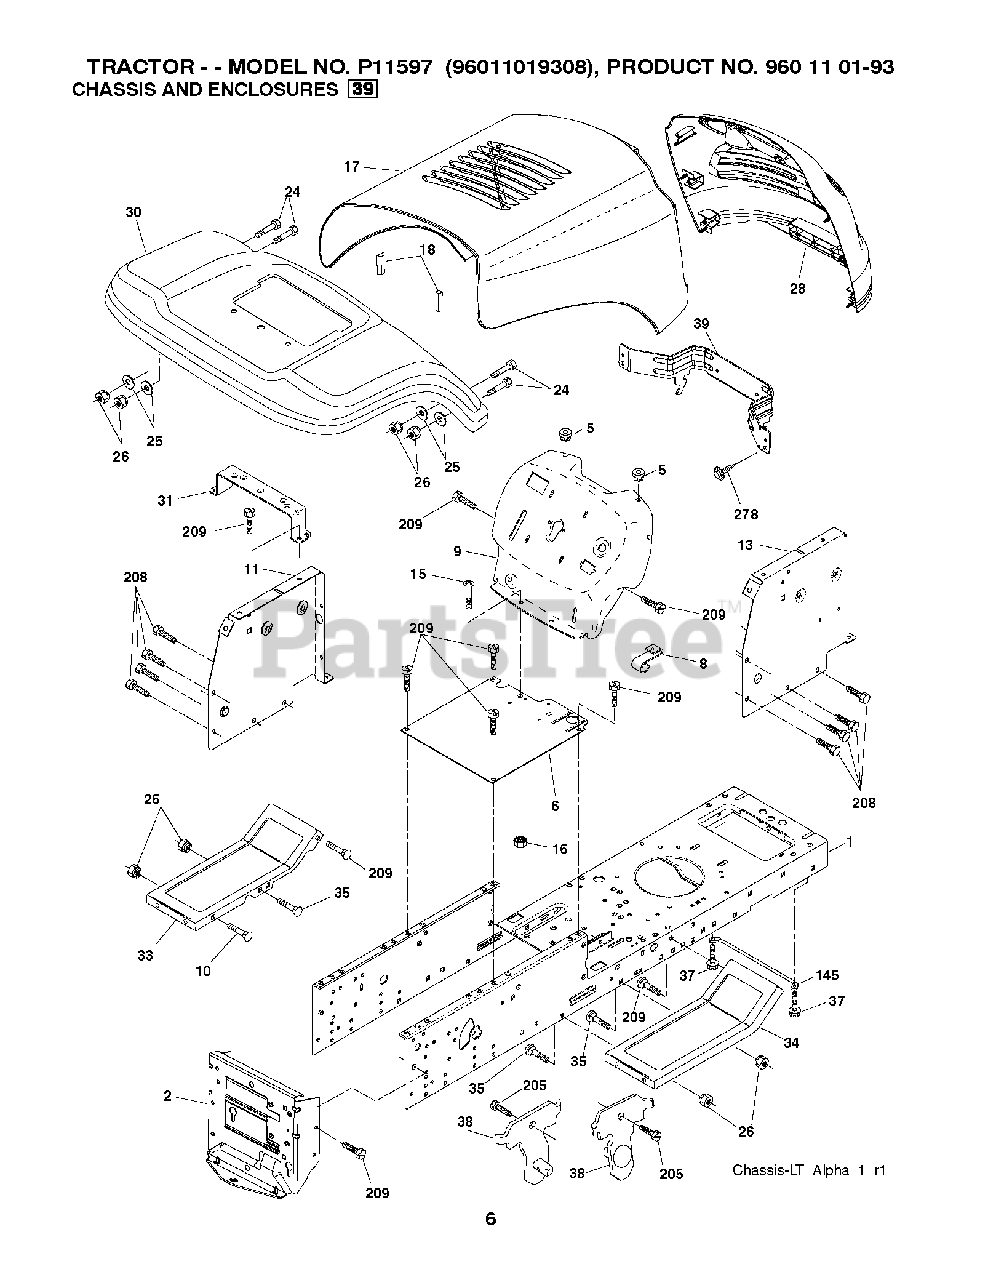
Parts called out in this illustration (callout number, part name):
1	CHASSIS
2	DRAWBAR, 12GA
5	BUMPER.RUBBER.HOOD
8	CLIP RETAINER
9	FENDER LT SH
10	BOLT D
11	PANEL.DASH.LH.LTX
13	PANEL DASH RH
16	NUT
17	HOOD.BLACK.ALPHA
18	BUMPER.HOOD.LARGE.1.75"
24	BOLT
25	WASHER
26	NUT
28	GRILLE.ALPHA.LT.NO LI
31	BRACKET FENDER
35	BOLT
37	SCREW LT
38	BRACKET.ASM.PIVOT.MOWER.REAR
39	BRACKET.PIVOT.ALPHA.LT
145	ROD.PIVOT.HOOD
205	SCREW LT
208	SCREW 3/8-16X1/2
209	SCREW, 3/8-16X3/4
278	SCREW.#10 X 0.750.BOS THREAD
